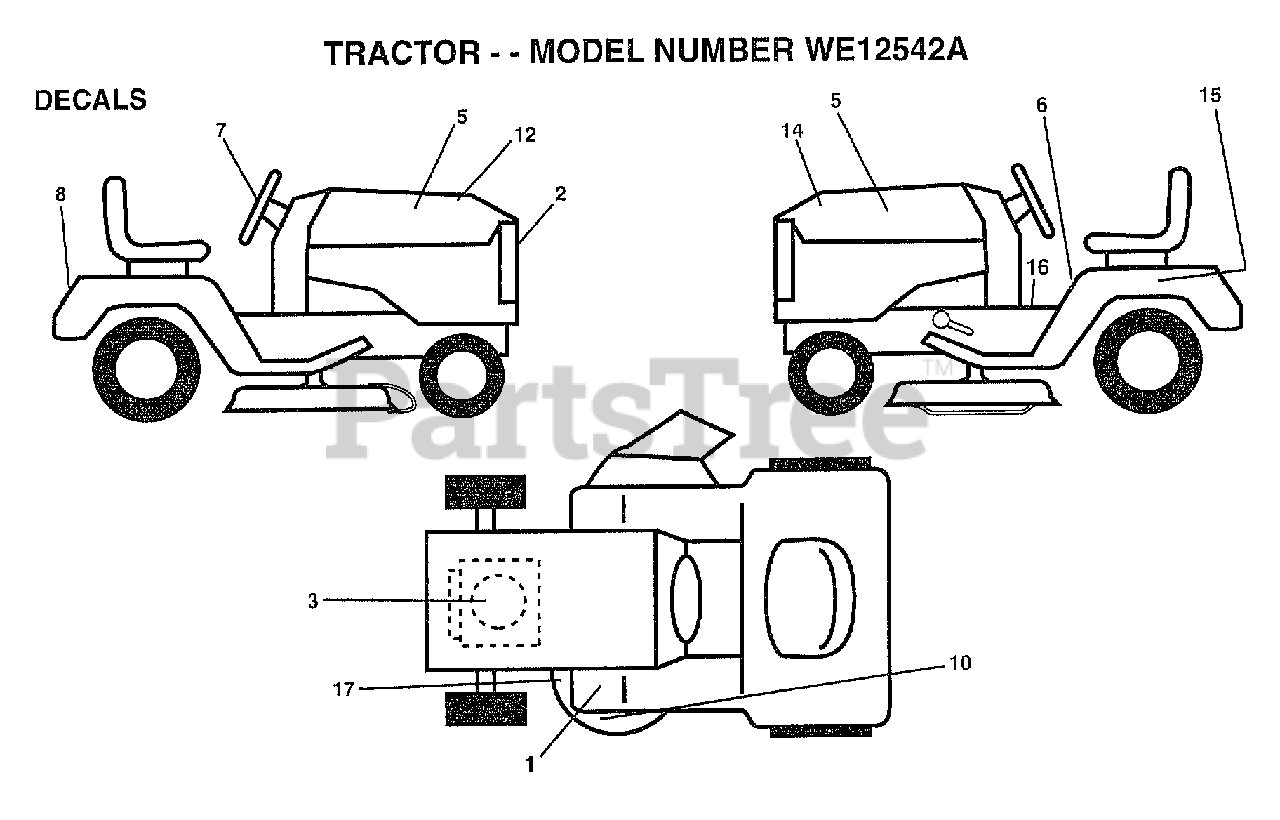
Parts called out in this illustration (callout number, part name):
2	"DECAL GRILLE,LENS"
3	DECAL, HP ENGINE
5	DECAL, PNL SD
6	"DECAL DANGER,FEND"
7	"DECAL INS,STRG WH"
8	DECAL-FENDER
12	"DECAL HOOD,RH"
14	DECAL HOOD LH
15	DECAL.BATRY.3-3908
16	"DECAL DASH,OPER."
17	"DECAL-SCHEM,BELT"
